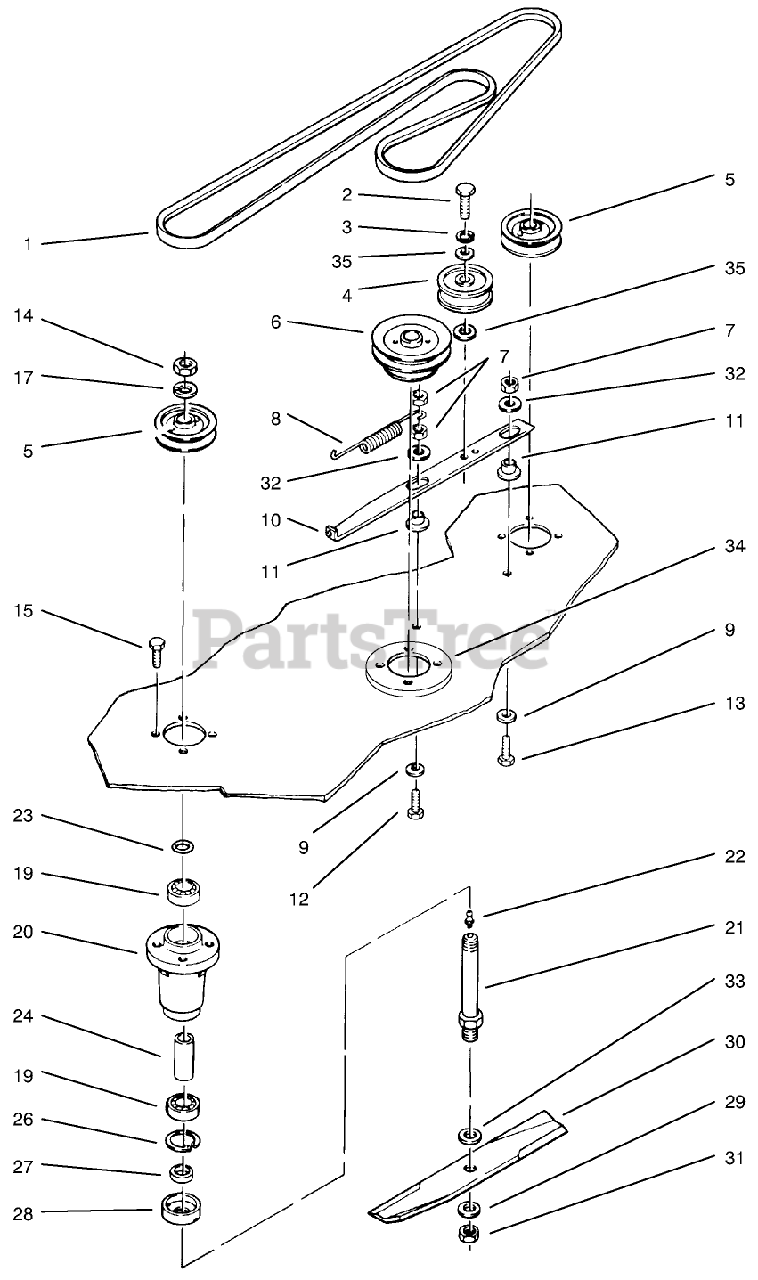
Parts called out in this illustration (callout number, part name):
1	V BELT
2	SCREW-HH
3	WASHER-LOCK
4	PULLEY-IDLER, FLAT
5	PULLEY
6	PULLEY
7	NUT-LOCK, NI
8	SPRING-EXTENSION
9	WASHER
10	BAR-IDLER SUPPORT
11	SPACER-BUSHING
12	SCREW-HH
13	SCREW-HH
14	NUT-JAM
15	SCREW-HH
16	Spindle Assembly (Incl. Ref.# 19-28)
17	WASHER-LOCK
19	BEARING-BALL
20	HOUSING-SPINDLE
21	SHAFT-SPINDLE
22	FITTING-GREASE
23	O RING
26	RING-RETAINING
27	SPACER-BLADE
28	CUP-SPINDLE
29	WASHER-FLAT
30	14IN BLADE KIT
31	NUT-JAM
32	WASHER
33	WASHER-FLAT
34	PLATE-SPINDLE
35	WASHER-FLAT
